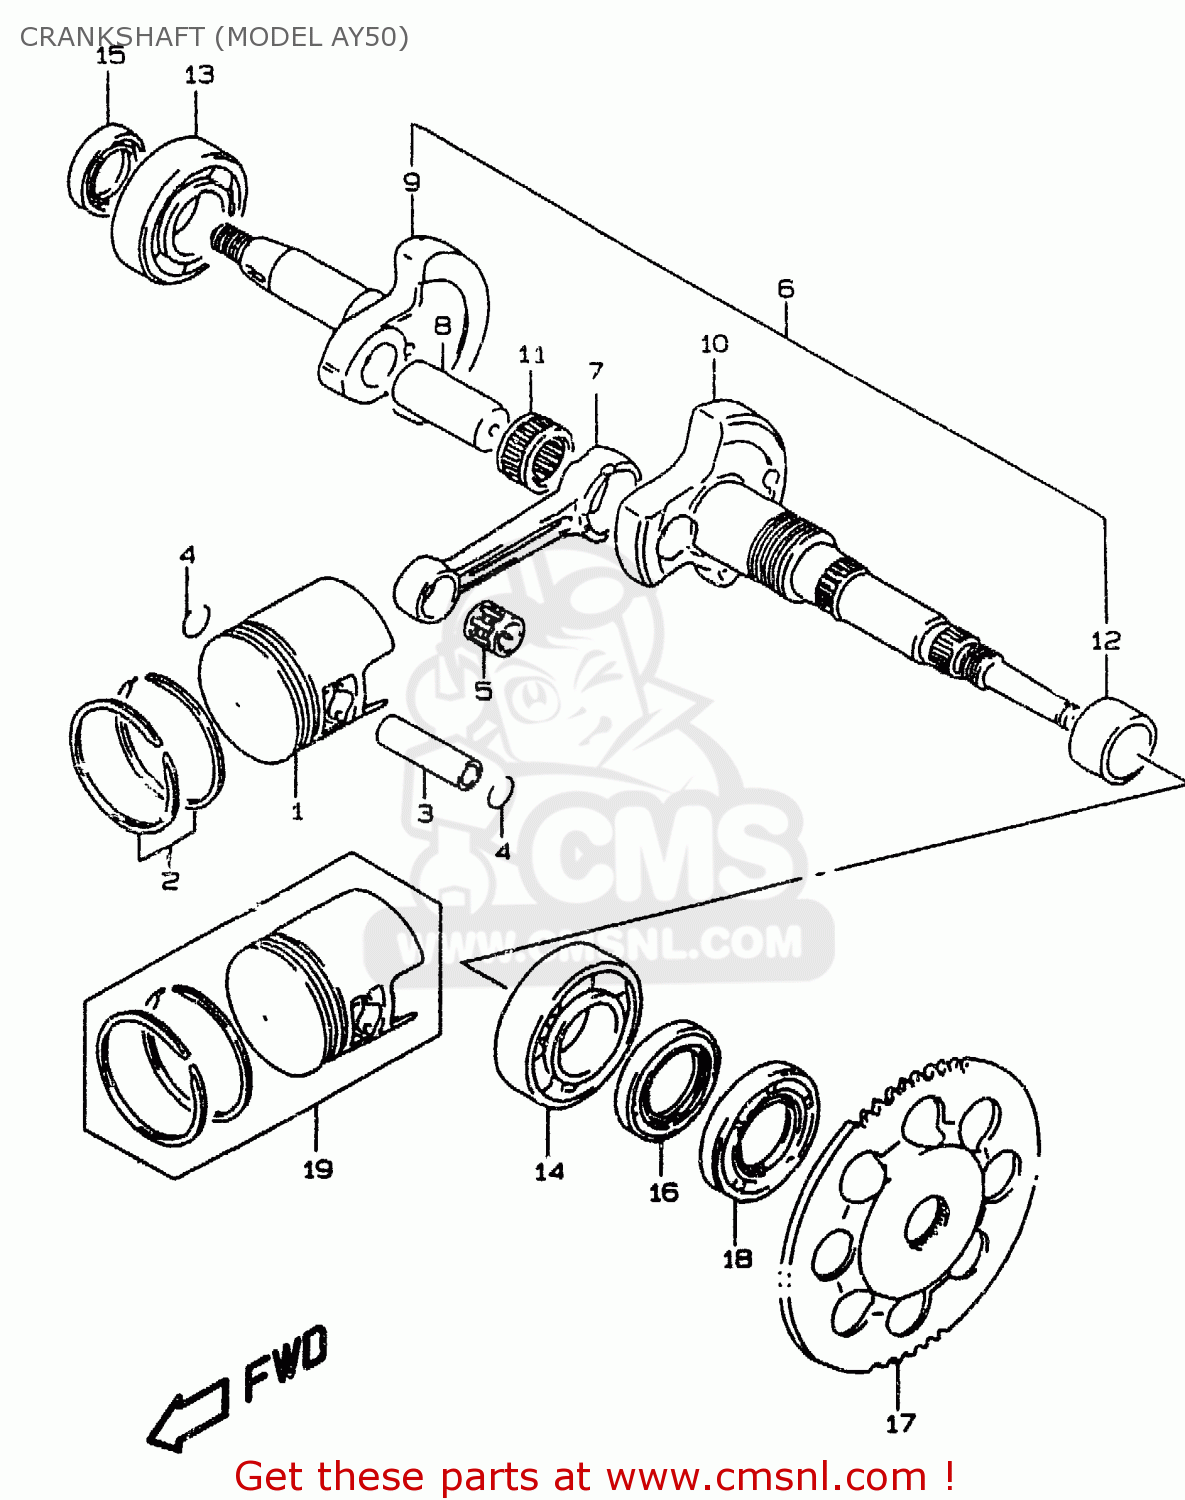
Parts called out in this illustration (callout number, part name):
1	PISTON (41.00MM)
2	RING SET,PISTON
3	PIN,PISTON
4	CIRCLIP
5	BEARING 10X14X12.5
6	CRANKSHAFT
7	CONNECTING ROD
8	PIN,CRANK
9	CRANKSHAFT,R
10	CRANKSHAFT,LH.
11	BEARING 16X22X12
12	SPACER(18X24X14)
13	BEARING 20X47X14
14	BEARING(25X52X13)
15	SEAL,OIL (17X27X6)
16	SEAL,OIL(25X37X6)
17	GEAR,STARTER
18	SEAL,OIL(24X43X6)
19	PISTON SET(OS:0.5)
